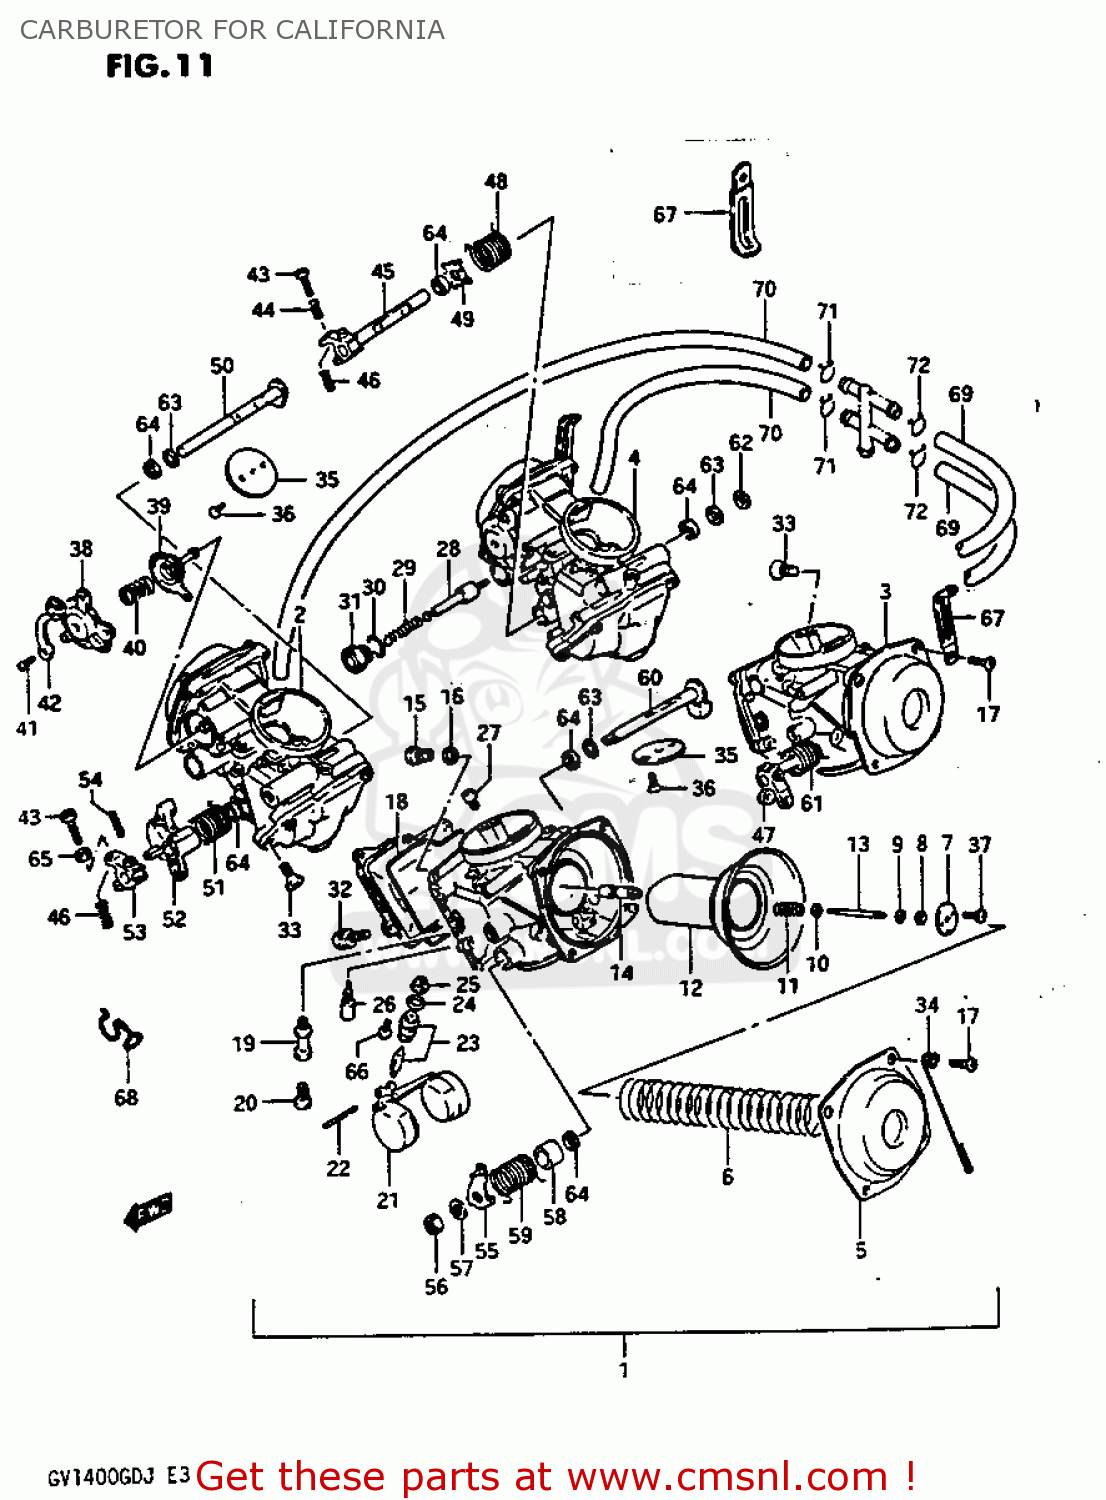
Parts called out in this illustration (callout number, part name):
1	CARBURETOR ASSEMBLY
2	CARBURETOR ASSEMBLY
3	CARBURETOR ASSEMBLY
4	CARBURETOR ASSEMBLY
5	COVER,DIAPHRAGM
6	SPRING,DIAPHRAGM
7	PLATE
8	RING
9	CLIP,NEEDLE
10	WASHER
11	SPRING
12	DIAPHRAGM,CARBURETOR
13	NEEDLE JET
14	JET,NEEDLE
15	SCREW
16	WASHER,NEEDLE NOZZLE
17	SCREW
18	O RING,FLOAT CHAMBER
19	HOLDER,MAIN JET
20	JET,MAIN(105)
21	FLOAT
22	PIN,FLOAT
23	VALVE ASSEMBLY,NEEDLE
24	O-RING,NEEDLE VALVE
25	FILTER
26	JET,PILOT(25)
27	JET,ENRICH
28	PLUNGER
29	SPRING,STARTER PLUNGER
30	O RING
31	HOLDER,GUIDE
32	SCREW
33	SCREW
34	CLIP
35	VALVE,THROTTLE
36	SCREW
37	SCREW
38	COVER
39	DIAPHRAGM ASSY
40	SPRING
41	SCREW
42	BRACKET
43	SCREW
44	SPRING
45	SHAFT,THROTTLE
46	SPRING,THROTTLE SCREW
47	SHAFT,THROTTLE
48	SPRING,THROTTLE VALVE
49	PLATE
50	SHAFT,THROTTLE
51	SPRING
52	LEVER,THROTTLE
53	LEVER,THROTTLE
54	PIN,THROTTLE SHAFT
55	LEVER,THROTTLE
56	NUT
57	WASHER
58	RING
59	SPRING
60	SHAFT,THROTTLE
61	SPRING,THROTTLE VALVE
62	E RING
63	GASKET,THROTTLE SHAFT (NAS)
64	SEAL,THROTTLE SHAFT
65	NUT
66	SCREW
67	CLAMP L:35
68	CLAMP
69	HOSE
70	HOSE
71	CLIP
72	CLIP
